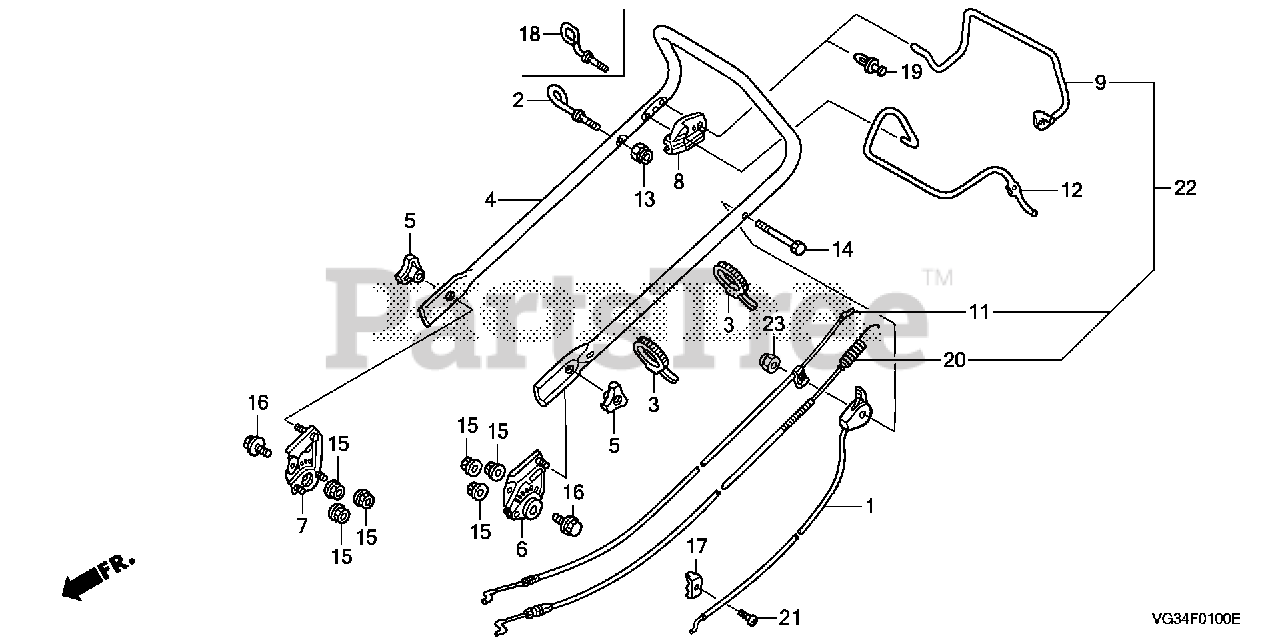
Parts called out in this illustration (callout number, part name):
3	TIE, CABLE (157.5MM)
4	PIPE, HANDLE *NH105* (MAT BLACK)
5	GRIP, HANDLE JOINT
6	STAY, L. HANDLE
7	STAY, R. HANDLE
8	STOPPER, LEVER
9	LEVER, CLUTCH
11	CABLE, BRAKE
12	LEVER, BRAKE
13	NUT, NYLON LOCK (6MM)
14	BOLT, FLANGE (6X45)
15	NUT, FLANGE (8MM)
16	BOLT, FLANGE (8X16)
18	GUIDE, ROPE
20	CABLE, CLUTCH
23	NUT, NYLON LOCK (6MM)
